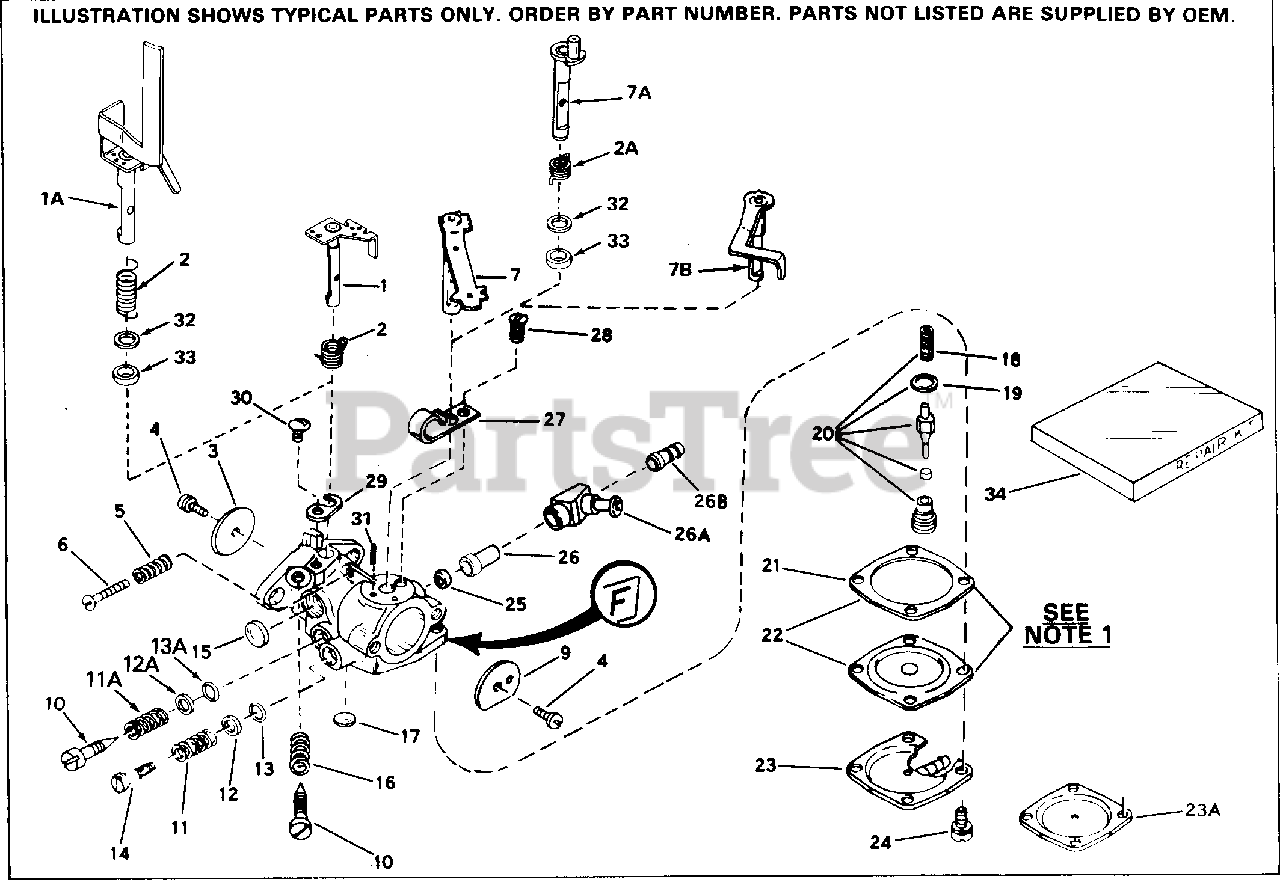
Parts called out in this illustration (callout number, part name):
1	"Shaft & Lever Assy., Throttle
2	Spring, Throttle return
3	Shutter, Throttle
4	Screw, Throttle & Choke shutter
5	Spring, Idle speed regulating
6	Screw, Idle regulating
7	Shaft & Lever Assy., Choke
9	Shutter, Choke
10	Screw, Idle adj.
11	Spring, Main adj. screw
12	Washer, Main adj. screw
13	"O" Ring, Main adj. screw
14	Screw, Main adj.
15	Plug, Welch
16	Spring, Idle adj. screw
17	Plug, Welch
18	Spring, Valve
19	Gasket, Valve seat
20	Inlet Needle, Seat, Spring & Gasket A ssy.
21	Gasket, Diaphragm
22	Diaphragm Assy.
23A	Cover, Diaphragm
26B	Fitting, Fuel inlet
27	Spring, Detent
28	Screw, Detent spring
29	Retainer, Throttle shaft
30	Screw, Throttle shaft retainer
34	Repair Kit
